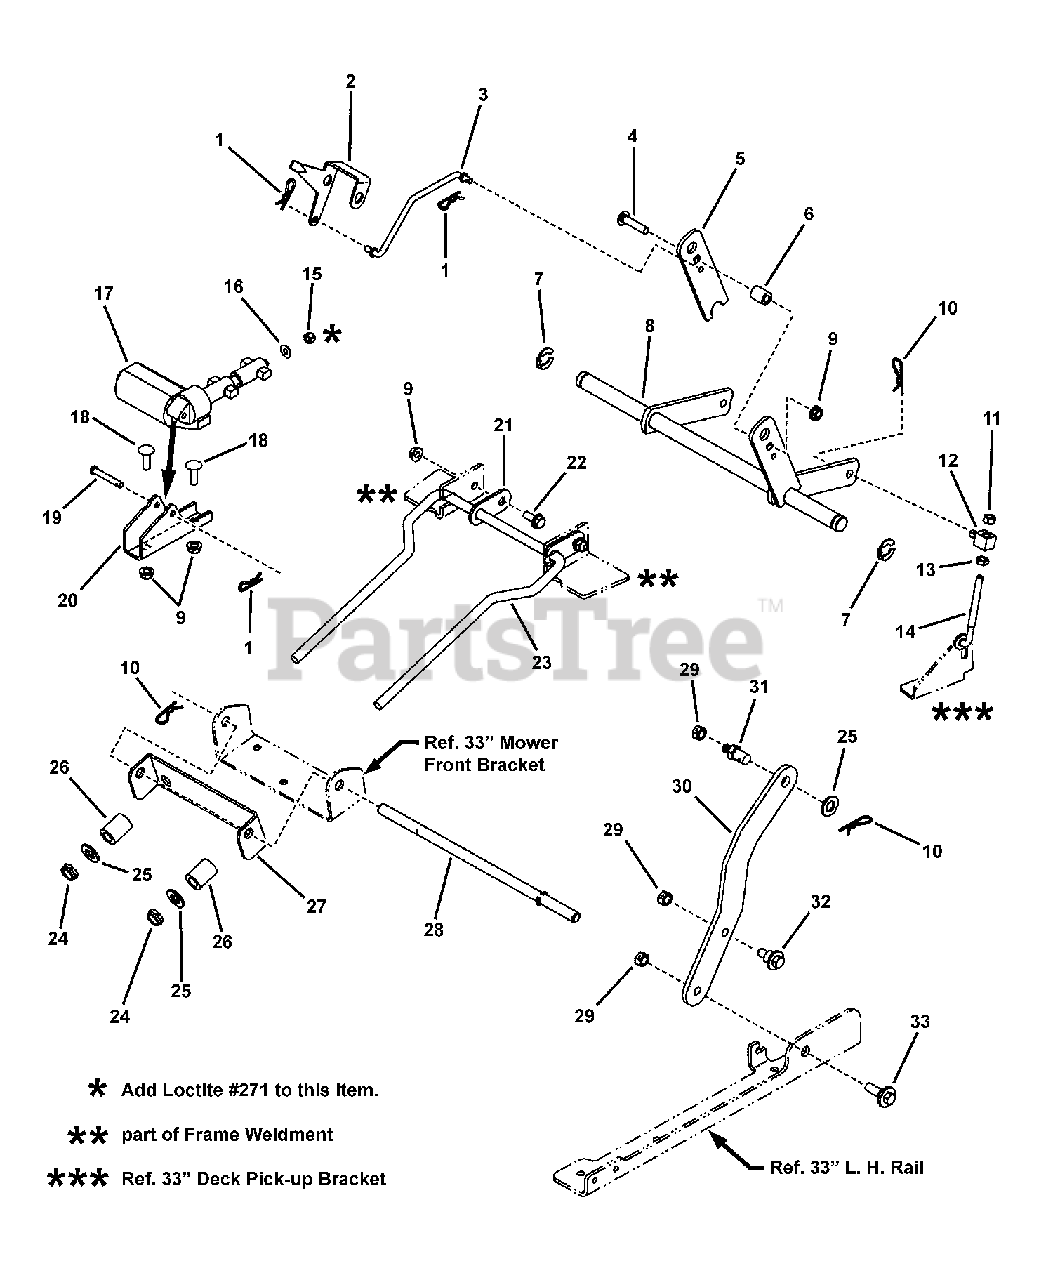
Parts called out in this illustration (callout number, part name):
1	CLIP, Hair Pin
2	INDICATOR, Height-of-Cut
3	ROD, Height-of-Cut Indicator
4	BOLT, 5/16-18 x 1-1/2" Round Head Short Square Neck, GR5
5	ARM, Lift Trunnion
6	SPACER, .328 I.D. x .625 O.D. x .781 Long (Powdered metal)
7	KLIPRING, External for .750 Dia. Shaft
8	WELDMENT, Lift Shaft, 33" Mower
9	NUT, 5/16-18 Hex Flange Lock, Small - Black
10	CLIP, Hair Pin .093 Dia.
11	NUT, 5/16-18 Hex Center Lock
12	SWIVEL, Brake Link (Powdered Metal)
13	NUT, 5/16-18 Hex Jam, Black
14	ROD, Height Adjust, 3.68"
15	NUT, 1/4-20 Hex, L.H. Thread
16	WASHER, 1/4" Flat (.27 I.D. x .62 O.D.)
17	MOTOR, Mini-Actuator (Electric)
18	BOLT, 5/16-18 x 1" Round Head Short Square Neck, GR5 Zinc
19	PIN, Shear
20	BRACKET, Electric Motor Mount
21	PLATE, Pivot Lock
22	SCREW, 5/16-18 x 3/4" Hex Flange Lock
23	ROD, Bail (1/2-13 thread, 2 places)
24	NUT, 1/2-13 Hex Jam
25	WASHER, 1/2" Flat (0.51 I.D. x 1.00 O.D. x .10 Thick)
26	SPACER, .520 I.D. x .88 I.D. x 1.185 Long
27	HANGER, Front
29	NUT, 3/8-16 Hex Center Lock
30	BAR, Rear Lift, 38/42
31	PIN, 3/8-16 Threaded Shoulder
32	SHOULDER BOLT, 3/8-16 x .600 O.D. x .95 Long
33	SHOULDER BOLT, 3/8-16 x .94
